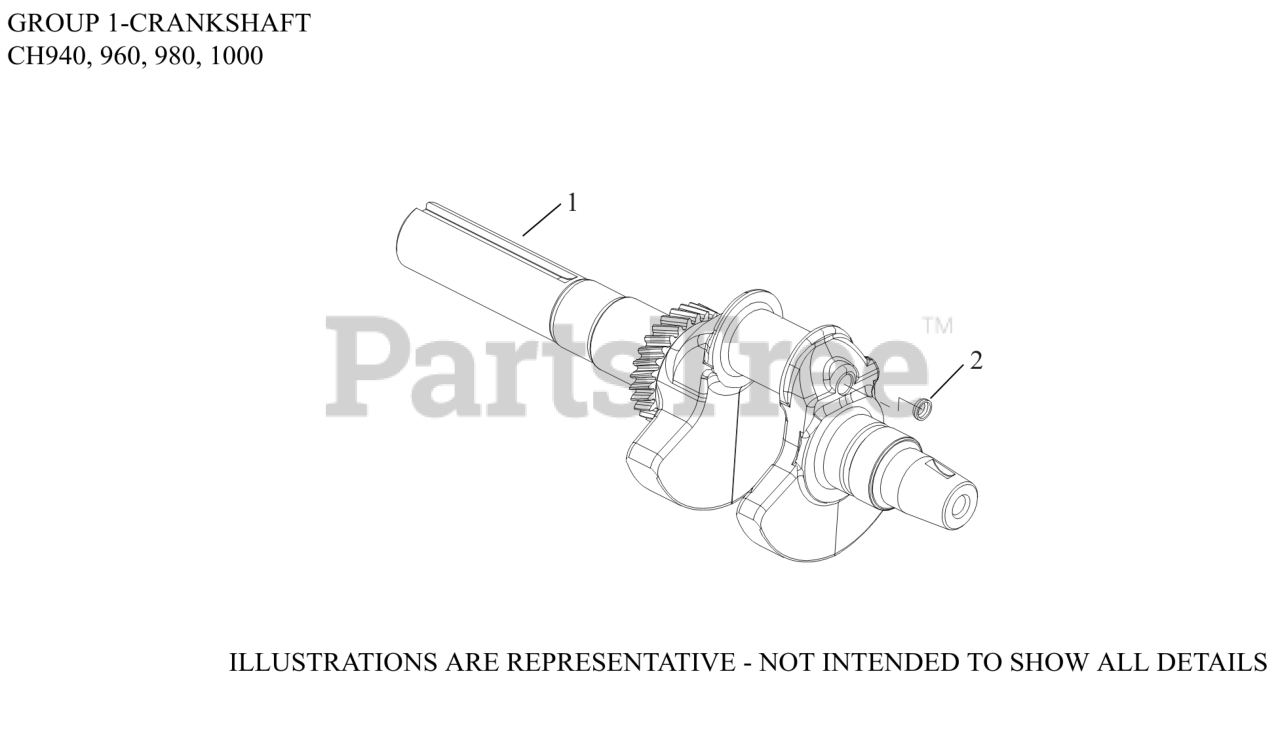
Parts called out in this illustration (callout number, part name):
1	CRANKSHAFT, FINISHED-DISCONTINUED
1	CRANKSHAFT, FINISHED
1	CRANKSHAFT ASSY-USE 62 014 105-S
2	PLUG, CUP
